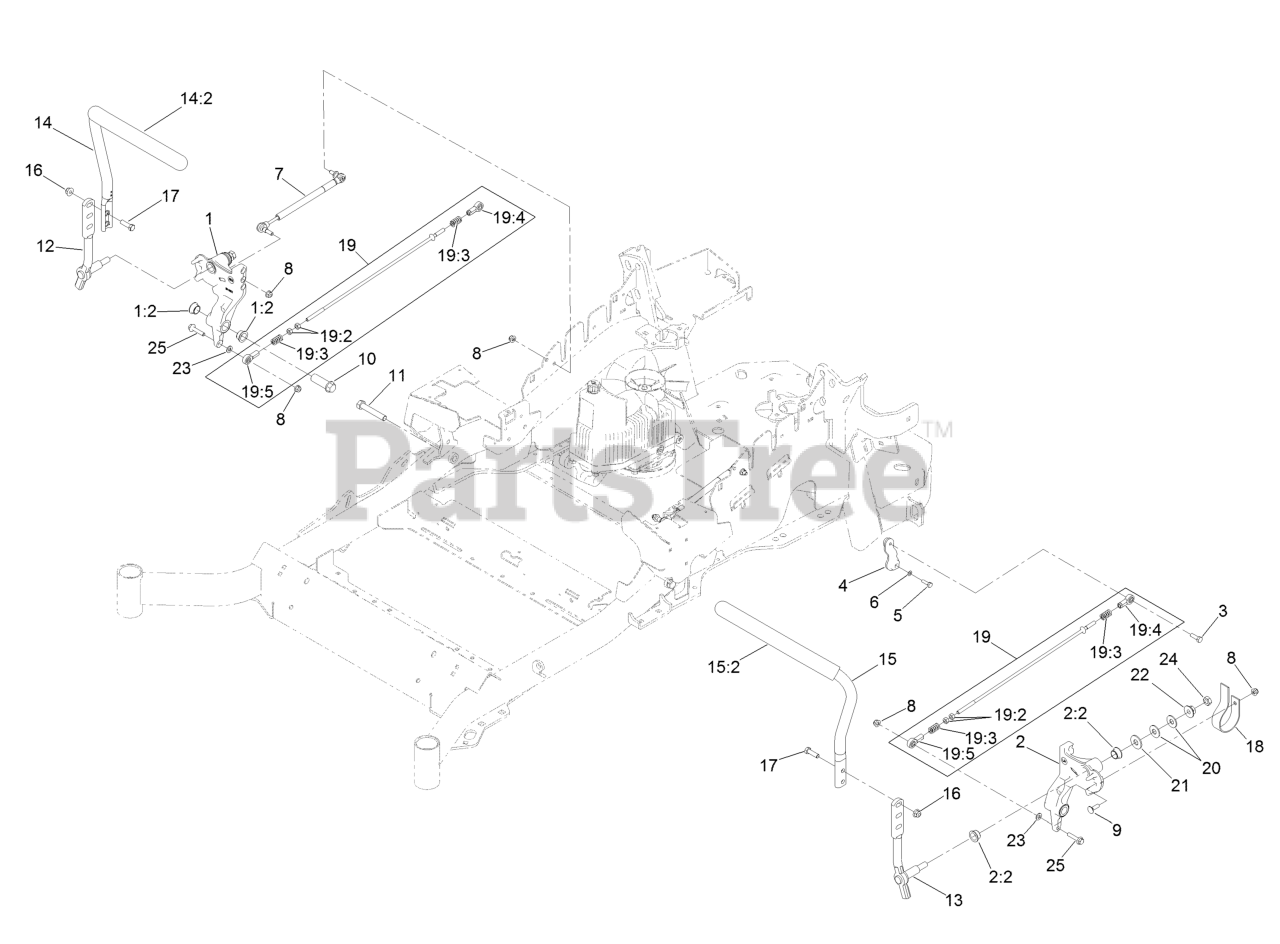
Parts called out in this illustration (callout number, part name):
1	RH MOTION CONTROL AND BUSHING ASM
1:2	BUSHING-FLANGE
2	LH MOTION CONTROL AND BUSHING ASM
2:2	BUSHING-FLANGE
3	SCREW-HH, THREAD LOCKING
4	ARM-CONTROL, PUMP
5	SCREW-HH
6	WASHER-SPRING
7	DAMPER-CONTROL, MOTION
8	NUT-HF, NI
9	BOLT-CARR
10	HUB-THREADED
11	SCREW-HH
12	LEVER-CONTROL MOTION, RH
13	LEVER-CONTROL MOTION, LH
14	RH STEERING HANDLE ASM
14:2	GRIP-LEVER, CONTROL
15	LH STEERING HANDLE ASM
15:2	GRIP-LEVER, CONTROL
16	NUT-HF, NI
17	SCREW-HH
18	SPRING-LEAF
19	FRONT PUMP LINKAGE ASM
19:2	NUT-HEX
19:3	SPRING-COMPRESSION
19:4	BALLJOINT-LH
19:5	BALLJOINT-RH
20	WASHER-SPRING
21	WASHER-FLAT
23	WASHER-PLAIN
24	NUT-JAM
25	SCREW-HHF
